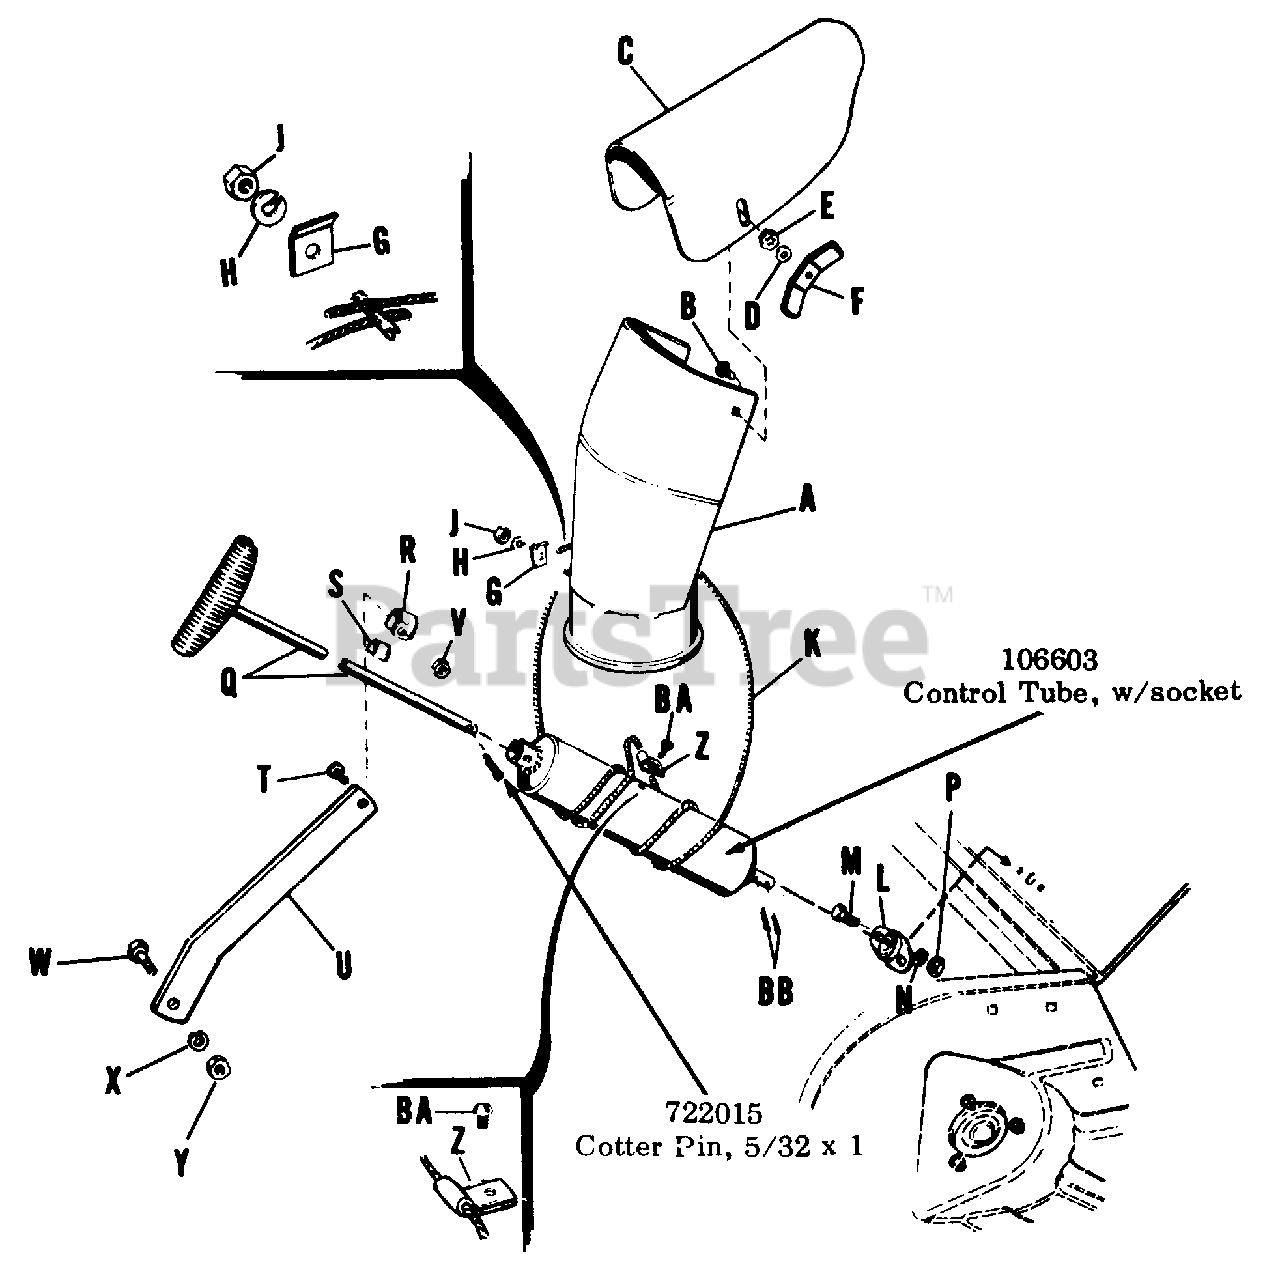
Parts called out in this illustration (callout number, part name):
A	Spout Assembly
B	Carriage Bolt, 5/16"-18 x 3/4" lg.
C	Spout Extenslon
D	Plain Washer, 3/8"
E	Lock Washer, Special, Hexagon, 3/8"
F	NUT, Wing, 5/16-18
H	Lock Washer, 5/16"
J	Hex Nut, Full, 5/16"-18
K	Spout Cord
M	Hex Capscrew, 1/4"-20 x 5/8" lg.
N	Lock Washer, 1/4"
P	Hex Nut, Full, 1/4"-20
Q	Spout Control Tube Assembly
S	Guide Liner
T	Hex Capscrew, 5/16-18 x 1 1 / 4 lg.
U	Rod Guide Support
V	Hex Lock Nut, Full, 5/16"-18
W	Hex Capscrew 3/8"-16 x 1-1/4" lg.
X	Lockwasher, 3/8"
Y	Hex Nut, 3/8"-16
BA	Self-Tapping Screw, 1/4 "-20 x 3/8 " lg.
BB	Cotter Pin, 1/8" x 3/4" lg.
